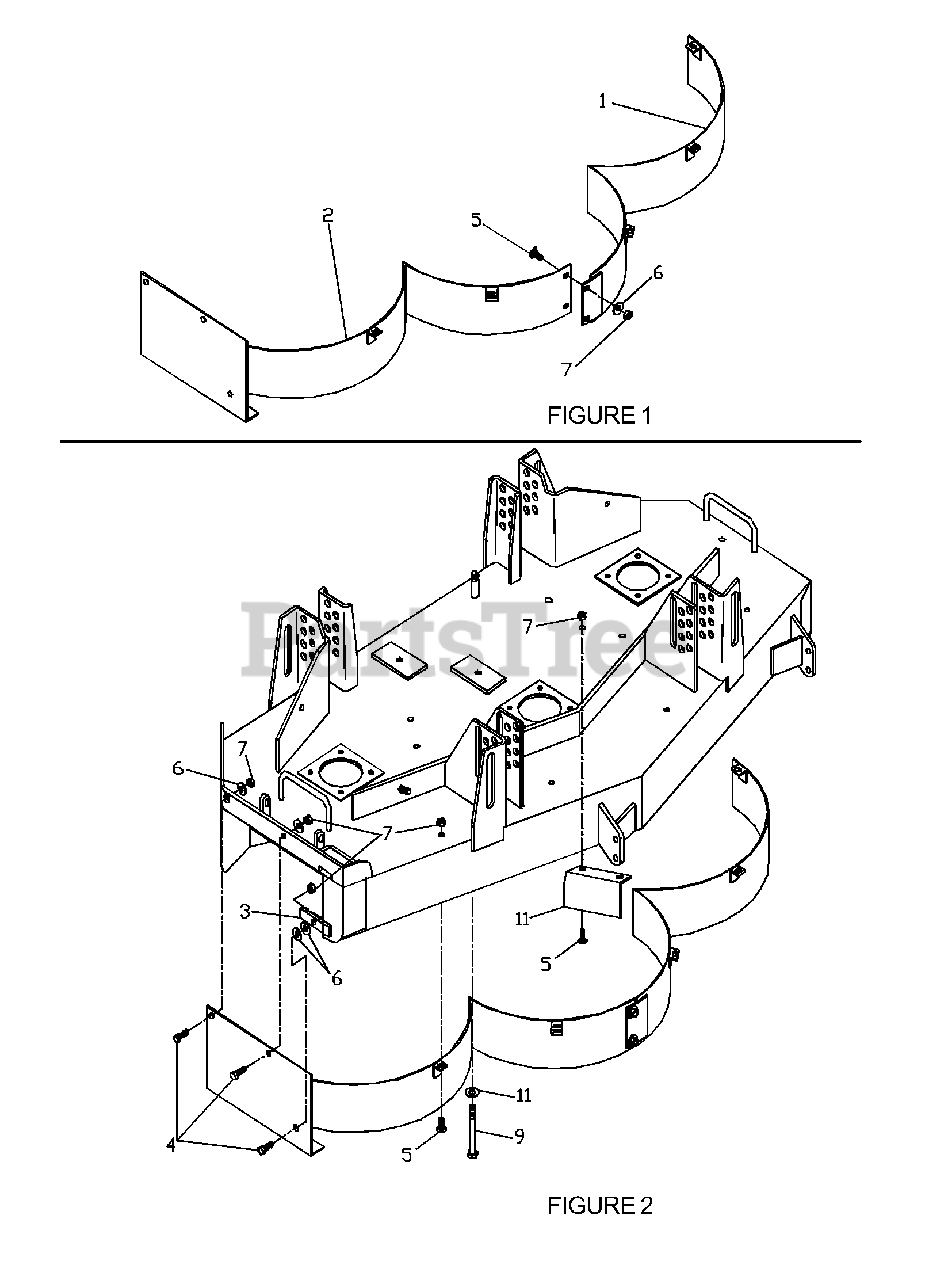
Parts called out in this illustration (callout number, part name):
1	BAFFLE, 42"
2	DISCHARGE BAFFLE, 42"
4	HCS 5/16C X 1" GRADE 5
5	5/16C X 5/8" CARRIAGE BOLT
6	5/16 FLAT WASHER
7	6 5/16C CENTERLOCK NUT
8	MULCH BLADE 14 7/8"
9	HCS 5/16C X 4 1/2"
10	CENTER DEFLECTOR
11	FLANGED WASHER
